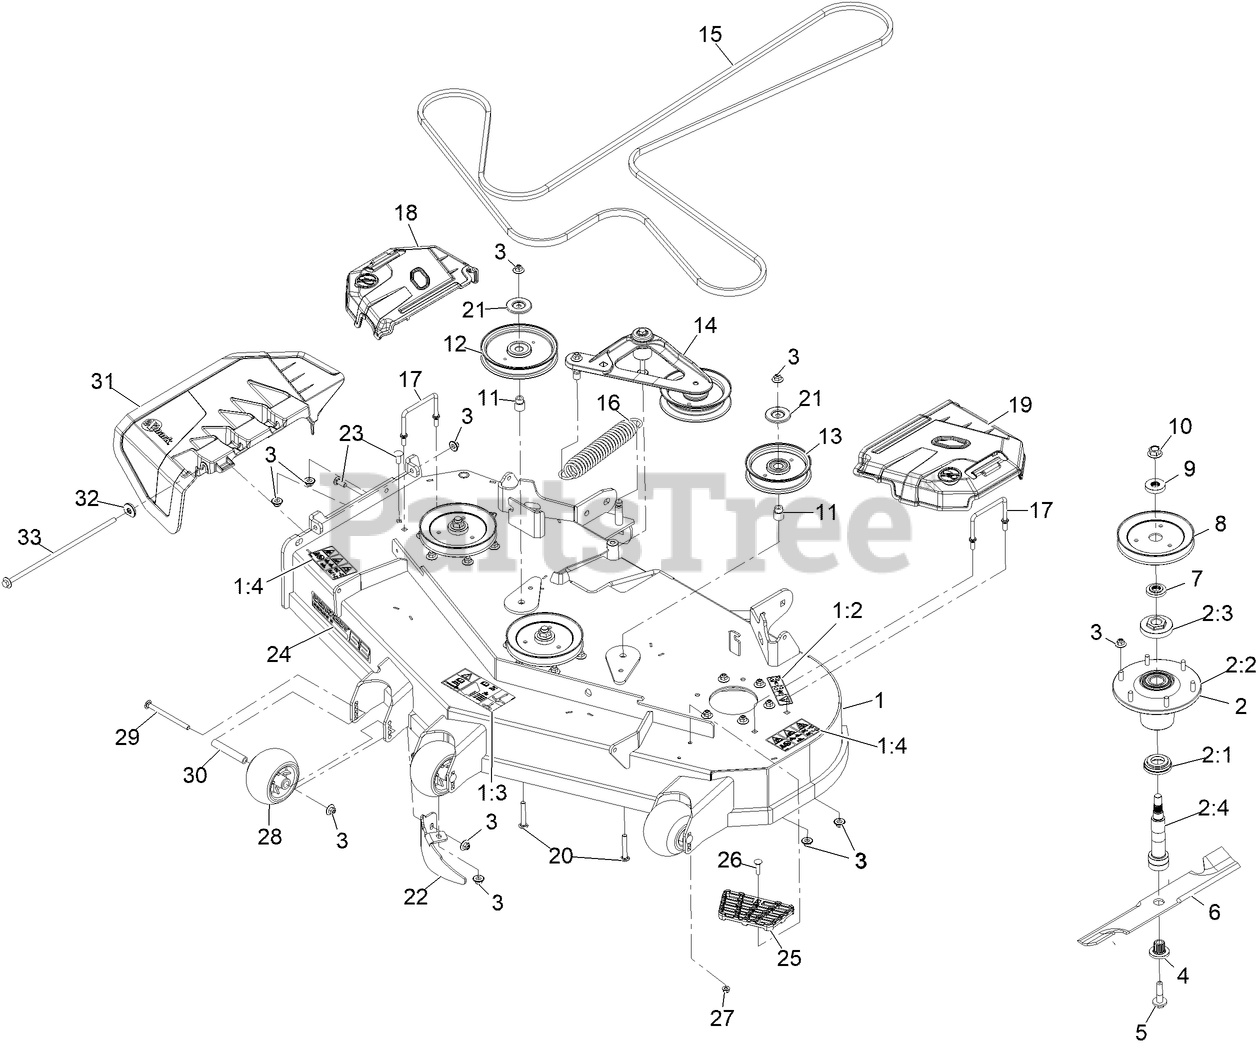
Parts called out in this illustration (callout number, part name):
1	ASM, Deck W/Decals 52
1:2	DECAL-COVER, MISSING
1:3	DECAL-ANTI-SCALP-BELT ROUTING
1:4	DECAL-DANGER THROWN OBJECTS
2	ASM,SPINDLE HOUSING
2:1	GUARD,BOTTOM
2:2	ASM,CUTTER HOUSING
2:3	NUT, SPINDLE 7/8-14
2:4	SPINDLE,DOUBLE SPLINE
3	Nut-Nyloc 3/8-16 Flg
4	BUSHING,SPLINED
5	SCREW,SEMS 1/2-20 X 2.19
7	SPACER,SPLINED STEPPED
8	SHEAVE,BLADE DRIVE
9	SPACER,SPLINED
10	NUT-FLANGE, CENTERLOCK
11	BUSHING-IDLER
12	Idler-Pulley, Flat
13	Pulley-Idler, Flat
14	ASM-IDLER, DECK
16	SPRING-EXTENSION
17	WIREFORM-COVER
18	SHIELD, RT
19	SHIELD, LT
20	SCREW-CARR
21	SHIELD-DUST
22	BAFFLE-DOGLEG, LZ-VT52
23	SCREW-CARR
24	Decal, 526
25	STEP-DECK
26	Bolt-Carriage 5/16-18 X 1 1/4
27	NUT-HF, NI
28	ROLLER-SCALP, ANTI
29	BOLT-CARR
30	SPACER-AXLE
31	Chute-Deck Discharge
32	Retainer, Chute
33	Pin, Chute
